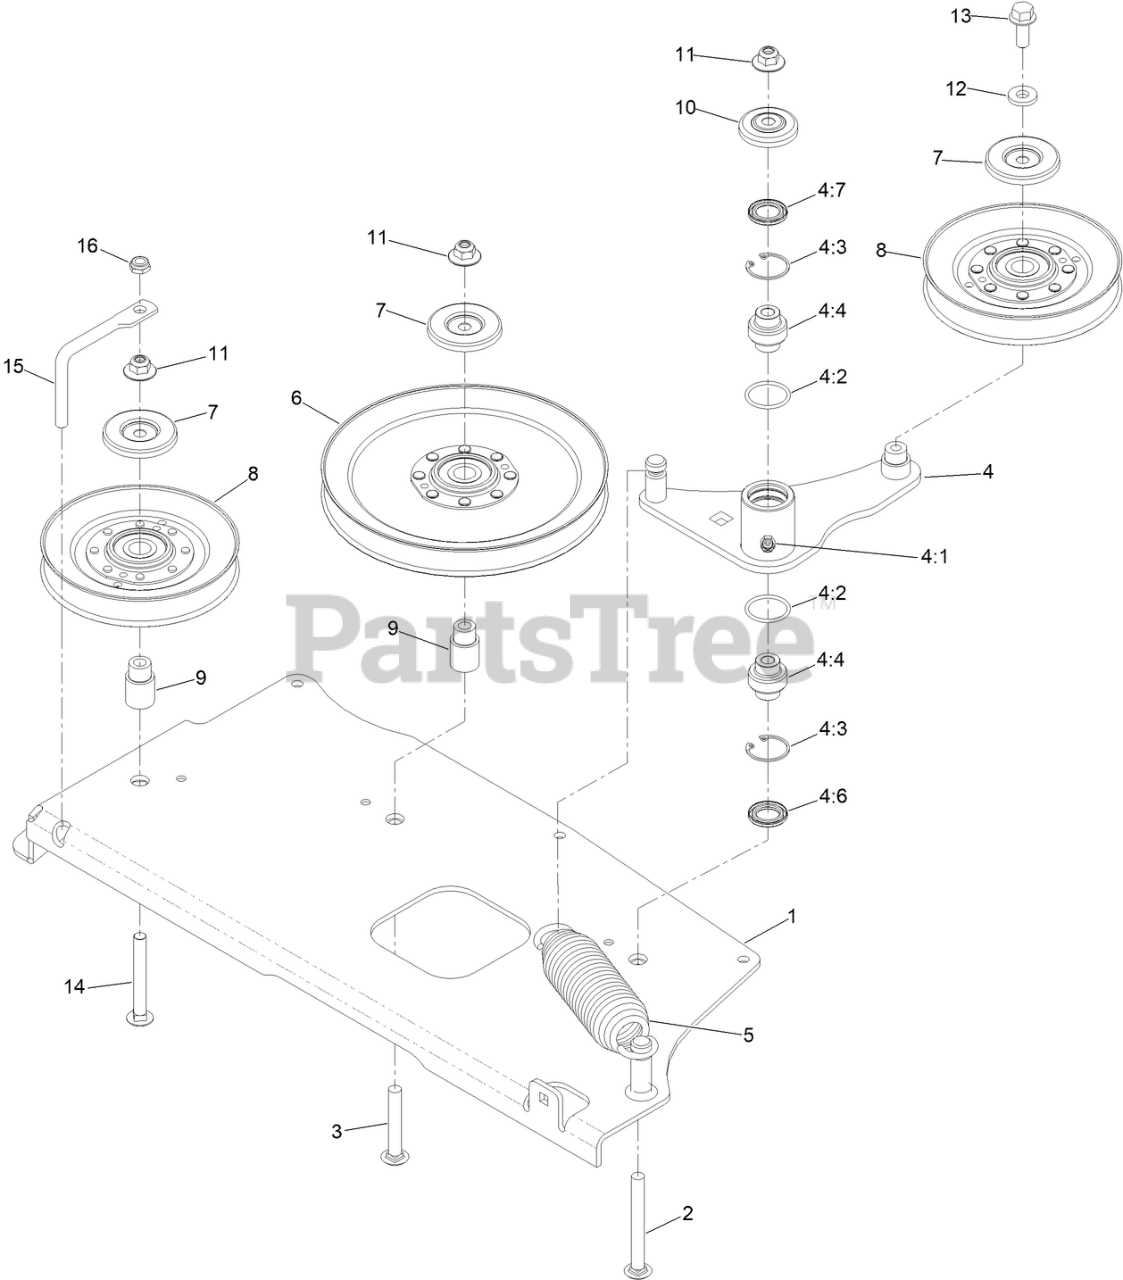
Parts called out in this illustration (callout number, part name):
1	MOUNT-IDLER
2	BOLT-SHOULDER, CARRIAGE
3	SCREW-CARR
4	IDLER ARM ASM
4:1	FITTING-LUBE, 45 DEG
4:2	O-RING
4:3	RING-SNAP
4:4	BEARING-SPHERICAL
4:6	SEAL-LIP, DOUBLE
4:7	SEAL-LIP, SINGLE
5	SPRING-EXTENSION
6	IDLER-V
7	SHIELD-DUST
8	IDLER V
9	STANDOFF-IDLER
10	GUARD-TOP
11	NUT-FLANGE, NI
12	SPACER
13	SCREW-HHF
14	SCREW-CARR
15	GUIDE-BELT
